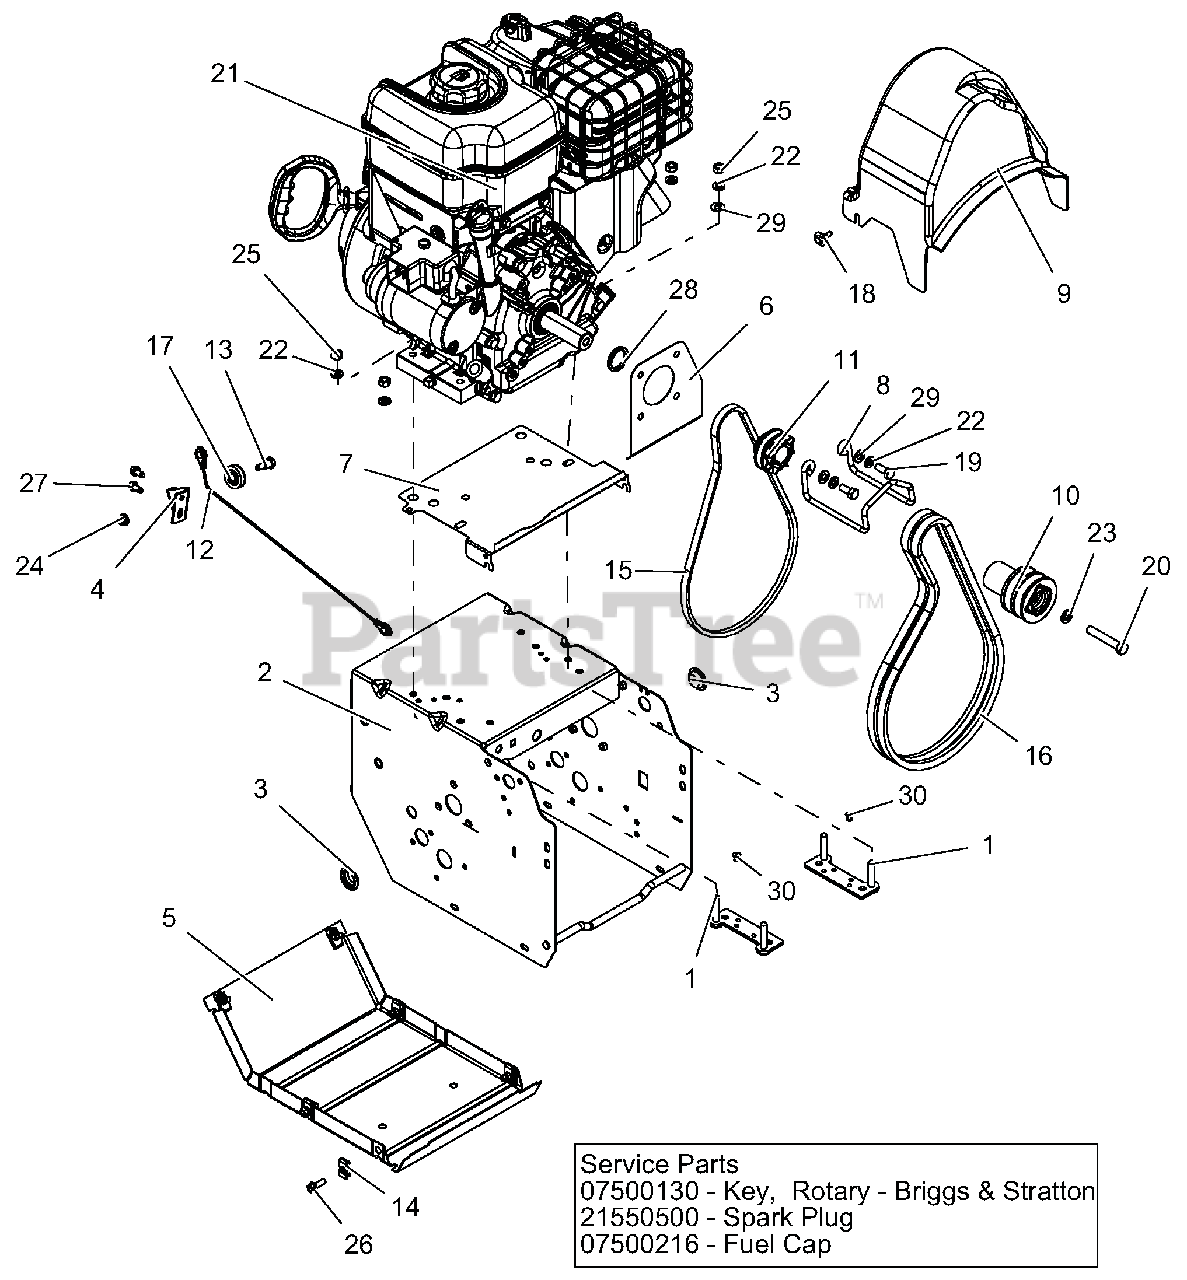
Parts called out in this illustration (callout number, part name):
1	STRAP, ENGINE BOLT-LARGE BRIGG
2	FRAME, 920/921
3	PLUG, HOLE - .875" NYLON
4	BRACKET, CABLE PULLEY
5	COVER, BOTTOM
6	BAFFLE, PRIMARY WATER
7	BAFFLE, BRIGGS MDL 20/21 WATER
8	FINGER, BELT
9	BELT COVER
10	SHEAVE,ATTACHMENT 2-GRV
11	SHEAVE, DRIVE
12	CABLE, LOWER TRACTION (DELUXE)
13	BOLT, SHLDR-.375X.375X.25-20
14	NUT-RTNR .25-20X.56
15	V-BELT, 3L-WRAPPED
16	V-BELT, HA-RAW EDGE (SET)
17	PULLEY, CABLE
18	SCR-TAP .25-20X.5 CAPTIVE
19	BLT-HEX .31-24X.75 YWZC GR5
20	BLT-HEX .38-24X2.25 YWZC GR5
21	ENGINE, BRIGGS SNOW 1650, 240V
22	WSHR-LK .312X.097 HVY YWZC
23	@WSHR-LK .38X.094 REG YWZC
24	@NUT-LK-CTR-FLG .25-20 YWZC
25	@NUT-HEX .31-18 YWZC
26	BLT-HEX .25-20X.75 HWH YZ GR5
27	SCR-TAP .25-20X.50 HWH TR YWZ
28	WSHR-FL-NYL 1.03 X 1.31 X .134
29	@WSHR-FL-STL.344X.688X.065YWZC
30	RVT-POP .187 YZ
